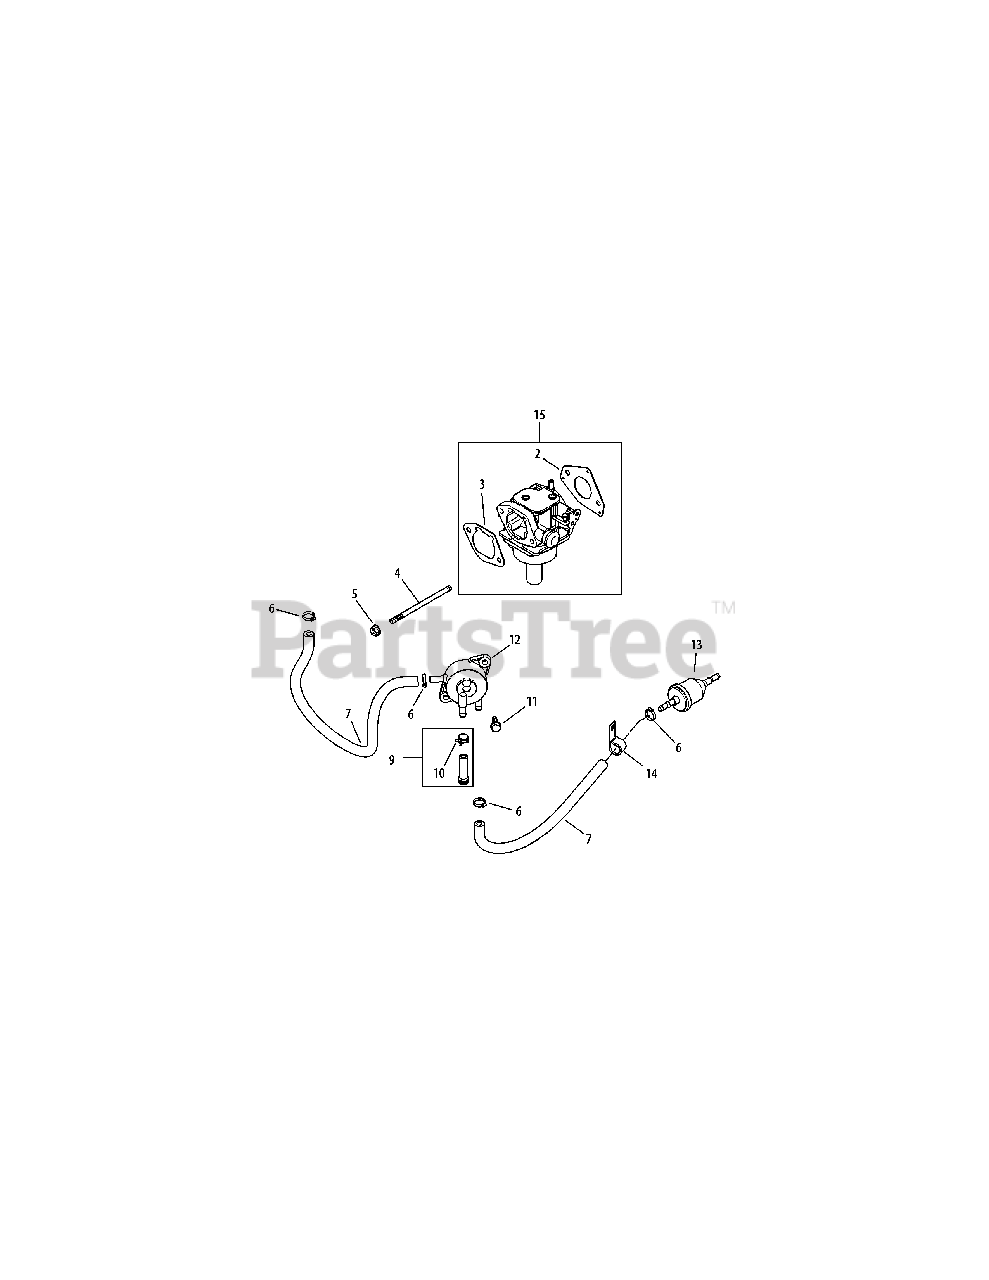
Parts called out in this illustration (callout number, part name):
2	Carburetor Gasket
3	Air Cleaner Base Gasket
4	Stud, M6 X 1.0 X 106
5	Flg. Nut, M6 X 1.0
6	Hose Clamp, 1/2
7	Fuel Line
11	Tap Screw, M6 X 1.7 X 18
15	Carburetor Kit, 19mm (Inc. 2 & 3)
